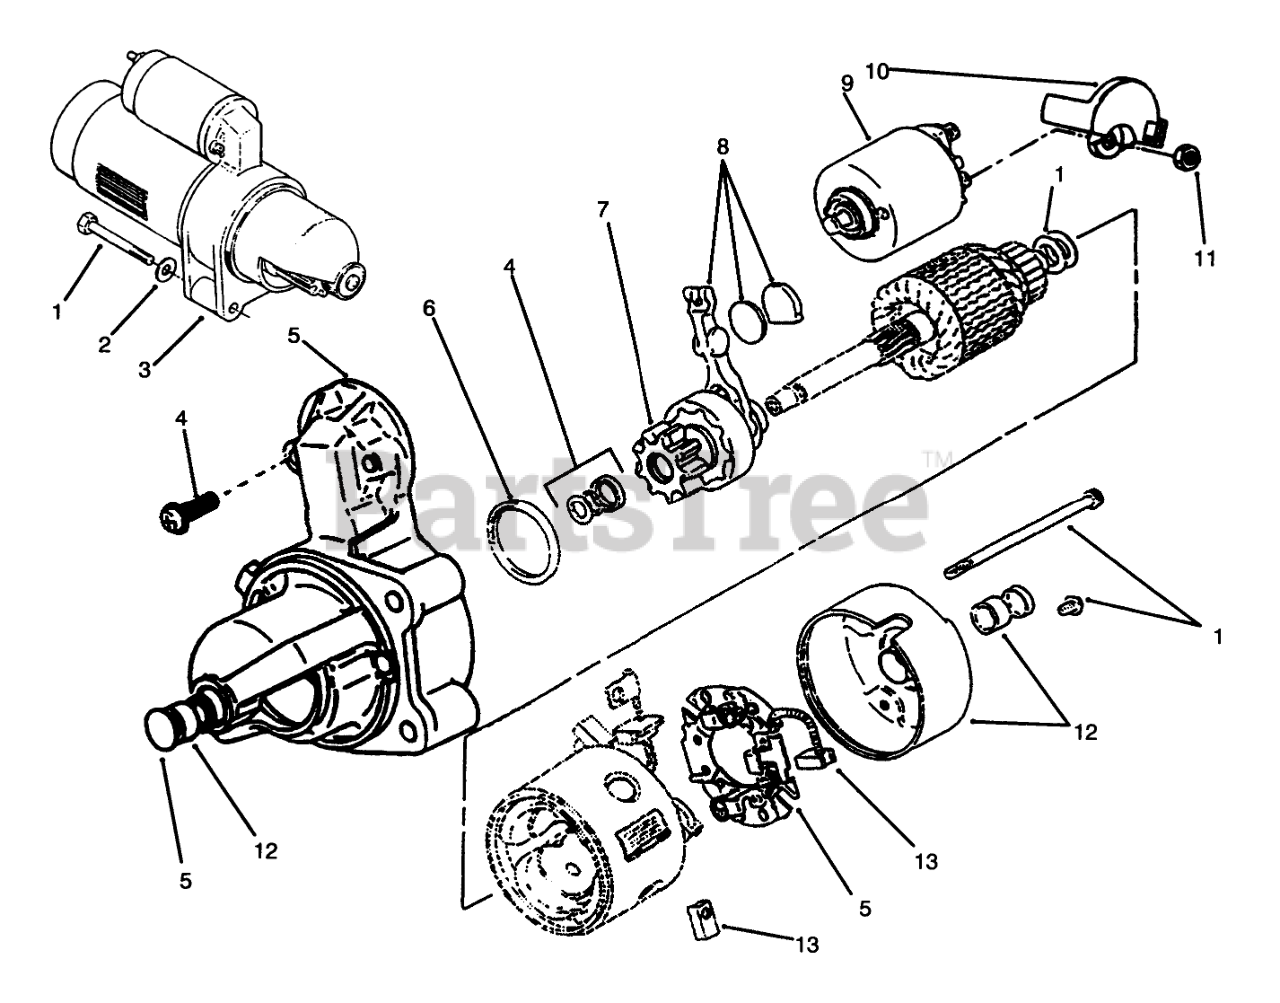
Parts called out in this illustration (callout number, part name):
1	SCREW
2	WASHER
3	STARTER
4	Kit-Hardware, Starter (Includes (2) Solenoid Mtg Screws, 2 Thru Bolts, Armature Shims, Pinion Collar, & Retaining Ring)
5	Kit-Mounting Bracket (Incl. Ref. #13)
6	DUST-SEAL KIT
7	Assembly-Clutch, Starter (Includes Pinion Gear)
8	Kit-Shift Lever, Starter (Includes Lever, Wear Plate & Rubber Plug)
9	Kit-Solenoid, Starter (Includes Solenoid & Spring Plunger)
10	Cap-Starter Solenoid
11	O-RING
12	Kit-Bushing, Starter (Incl. Rear Cap with Bushing & Front Bushing)
13	Kit-Brush, Starter (Includes (2) Negative & (1) Positive Brushes)
